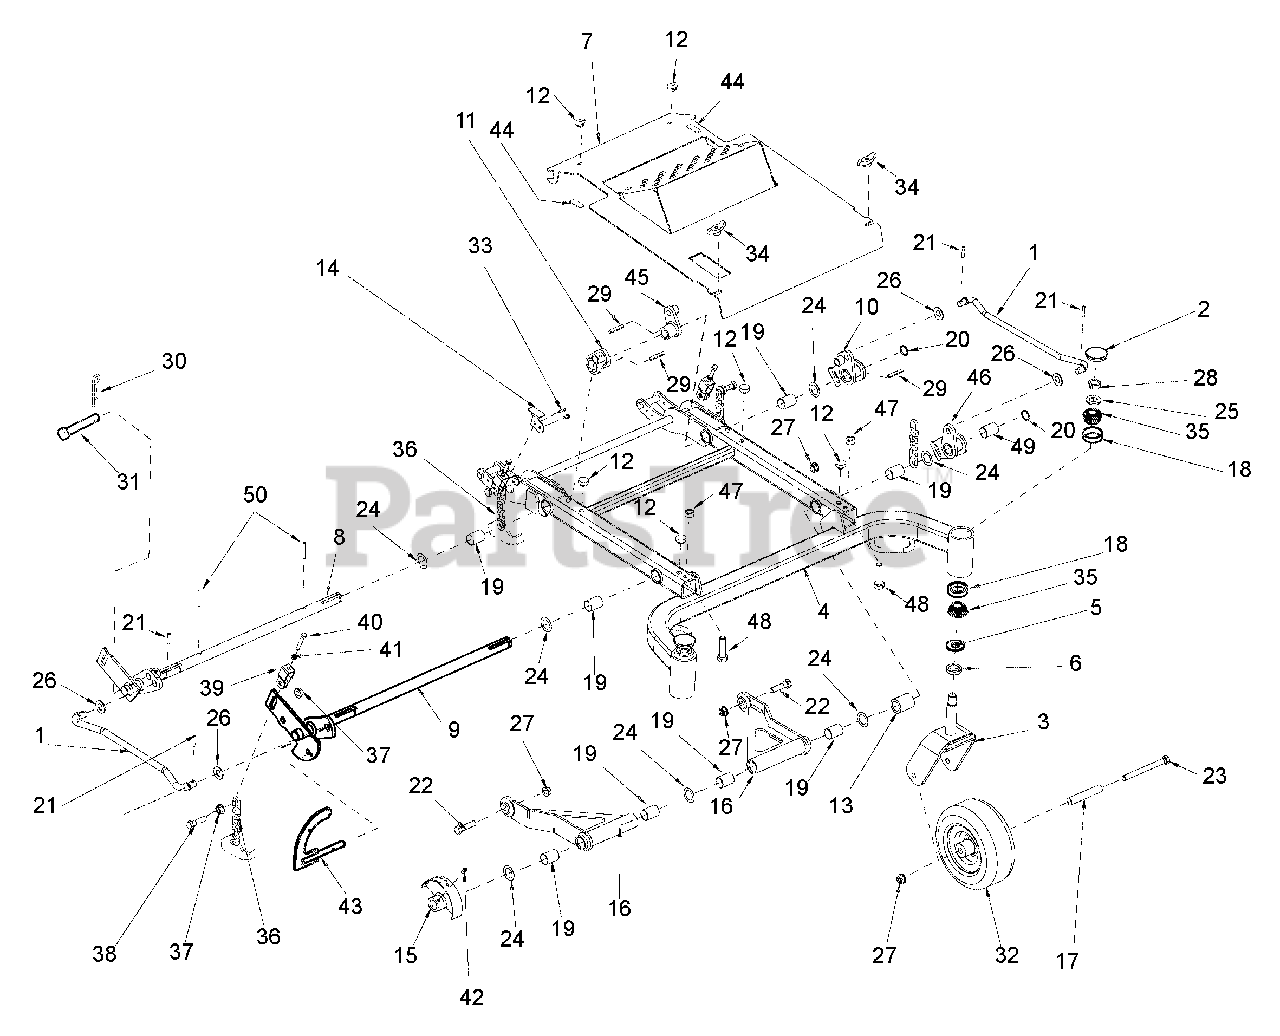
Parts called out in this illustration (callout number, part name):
1	Rod, Lift Assist 19.35
2	Cap, Dust
3	Weldment, Caster Fork (Outfront)
4	Weldment, Carrier Frame (Outfront)
5	Bearing Seal 1.5 x 2 x .18
6	Spacer 1.005 x 1.5075 x .375
7	Weldment, Carrier Foot Plate 72"
8	Weldment, Shaft, Deck Lift
9	Weldment, Shaft, Deck Lift
10	Weldment, Lift Arm, 72" Rapid XZ
11	Weldment, Mower Lift To Cylinder Arm
12	Bumper, Rubber Snap In
13	Spacer, 1.0 ID x 1.5 OD x 1.81 Lining
14	Lever, Deck Tilt PTO Switch
15	Cut Indicator - Red
16	Weldment, Mower Mounting Arm
17	Bearing .532 x .750 x 4.06
18	Bearing, Cup 1.980 x .420
19	Bushing 1.00 ID x 1.125 OD x 1.50 LG
20	Ring, Retaining-External 1.00 x .078
21	Pin, Roll .250 x 1.25 Stainless Steel
22	Bolt, Hex .50-13 x 2.00 Grade 5
23	Bolt, Hex .50-13 x 5.50 Grade 5
24	Washer, Hardened-Thrust 1.00 x 1.55 x .03
25	Washer ,Flat Steel .812 x 1.50 x .135 YWZC
26	Washer, Flat Steel .656 x 1.31 x .095 YWZ
27	Nut .50-13 Nyloc Flange
28	Nut, Jam Center-Lock .75-16
29	Key, Straight .25 x 1.75 x .25
30	Pin, Hair-Internal .15 x 2.937
31	Pin, Clevis .625 x 4.0
32	Wheel Assembly 9.00 x 3.50-4
33	Screw, Tapping 12-24 x .50 Hex Washer Head Thread Rolling (Lubricated Or Waxed)
34	Knob, Clamping .312-18 Nyloc
35	Bearing, Cone with Grease
36	Chain, Link
37	Nut, Spinlock Flange M12-1.75
38	Bolt, Hex M12-1.75 x .50 Class 8.8
39	Bracket, Deck Leveling
40	Bolt, Hex .312-18 x 2.00 FTH Grade 5
41	Nut, Jam .312-18
42	Screw, Set .25-20 x .50 EP80
43	Pin, Deck Tilt (shipped loose in literature package)
44	Tape, Foam .12 x 1.0 x 2.50
45	Arm, Deck Lift
46	Weldment, LH Deck Lift Arm
47	Nut, Locking Center .31-18
48	Bolt, Hex .31-18 x 1.25
49	Bushing, 1.00 X 1.125 X 1.936
50	Pin, Roll .125 x 1.38
